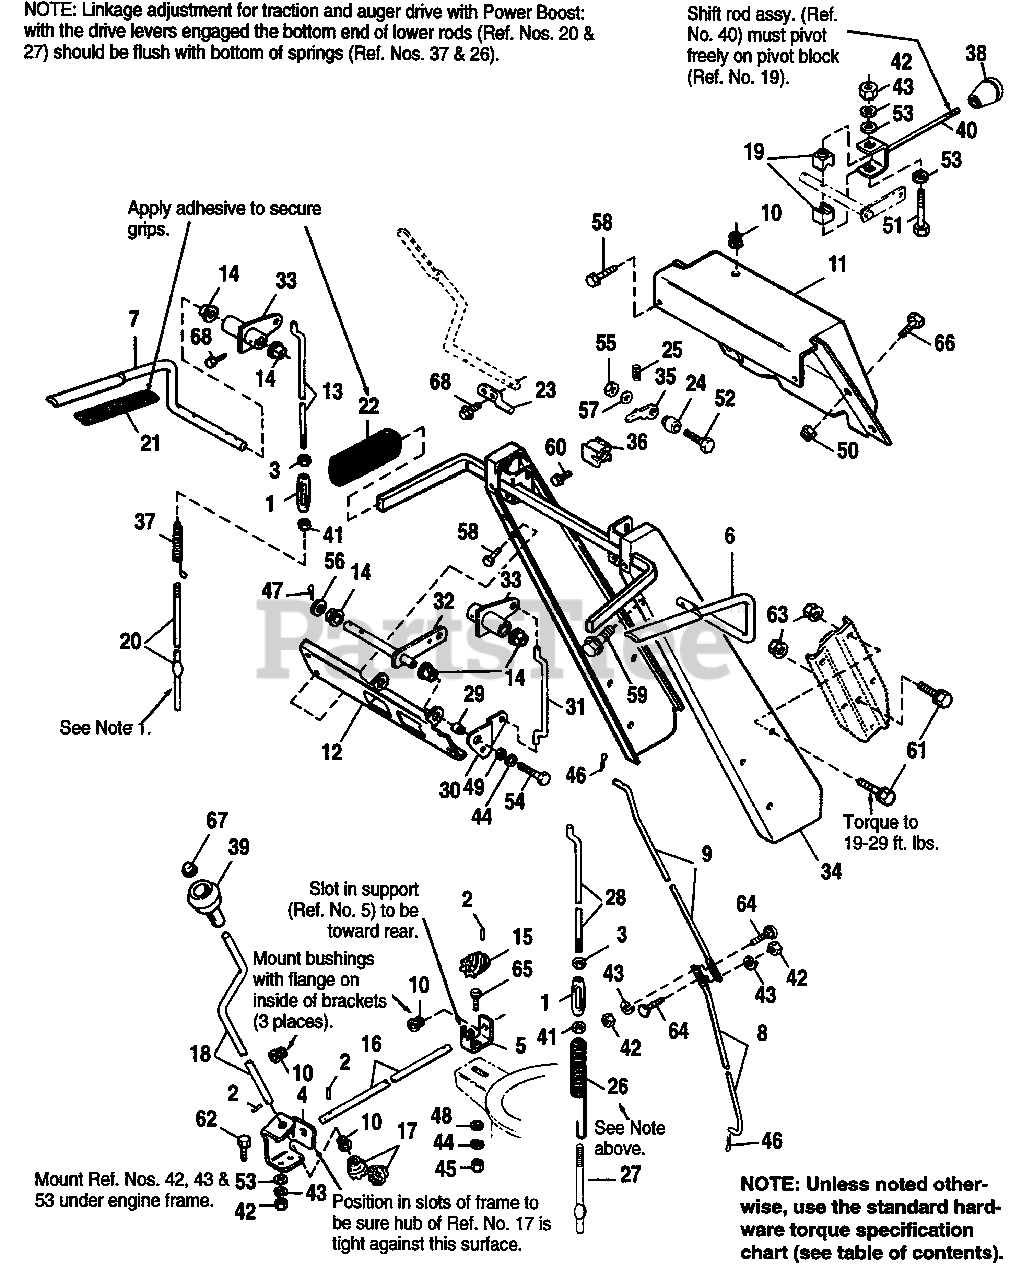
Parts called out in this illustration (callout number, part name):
2	PIN, Roll, 1/8 x 3/4
3	NUT, Hex, #10-24, LH
4	SUPPORT, Universal Gear
5	SUPPORT, Worm
6	HANDLE, Clutch RH
7	HANDLE, Clutch, LH
8	ROD, Shift-Lower
9	ROD, Shift-Upper
10	BUSHING, Plastic
11	DASH, Handle
12	BRACKET, Shift Control
13	ROD, Clutch-Upper
14	BUSHING, Plastic
15	WORM, Chute
16	ROD, Chute Worm
17	GEAR, Universal
18	ROD, Chute Control
19	BLOCK, Pivot
20	ROD, Clutch-Lower, Traction
21	GRIP, Clutch
22	GRIP, Handle Bar
23	ROD, Control
24	SPACER, Special
25	SPRING
26	SPRING, Extension
27	ROD, Clutch-Lower, Auger
28	ROD, Clutch-Upper, Auger
30	LEVER, Clutch
31	ROD, Clutch
32	PIVOT ROD ASSY.
33	CLUTCH LEVER ASSY.
34	HANDLE ASSY.
35	LATCH, Control
36	GUIDE, Control
39	KNOB, Spinner
40	SHIFT ROD ASSY.
41	NUT, Hex, #10-24, RH
42	NUT, Hex, 1/4-20
43	LOCKWASHER, 1/4
44	LOCKWASHER, 5/16
45	NUT, Hex, 5/16-18
46	PIN Cotter
47	PIN, Cotter, 1/8 x 1
48	WASHER, Flat, 11/32
49	WASHER, Plain, 5/16 x 1
50	NUT, Nylon Lock, 1/4-20
51	CAPSCREW, Hex Hd., 1/4-20 x 2-1/4
52	CAPSCREW, Hex Hd., 5/16-18 x 1-1/2
53	WASHER, Flat, 9/32
54	CAPSCREW, Hex Hd., 5/16-18 x 1-3/4
55	NUT, Hex, Lock, 5/16-18
56	WASHER
57	WASHER, 13/32
58	SCREW, Taptite, 1/4-20 x 1/2
59	SCREW, Hex, Washer Hd., Taptite, 1/4-20 x 3/8
60	SCREW, Taptite, #10-32 x 1.00
61	CAPSCREW, Whizlock 5/16-18 x 3/4
62	CAPSCREW, Hex Hd., 1/4-20 x 3/4
63	NUT, Hex, Flange, Whizlock 5/16-18
64	CARRIAGE BOLT, 1/4-20 x 3/4
65	CARRIAGE BOLT, 5/16-18 x 3/4
66	CAPSCREW, Washer Hd., 1/4-20 x 3/4
67	PALNUT
68	SCREW, Taptite, #12-24 x 1
